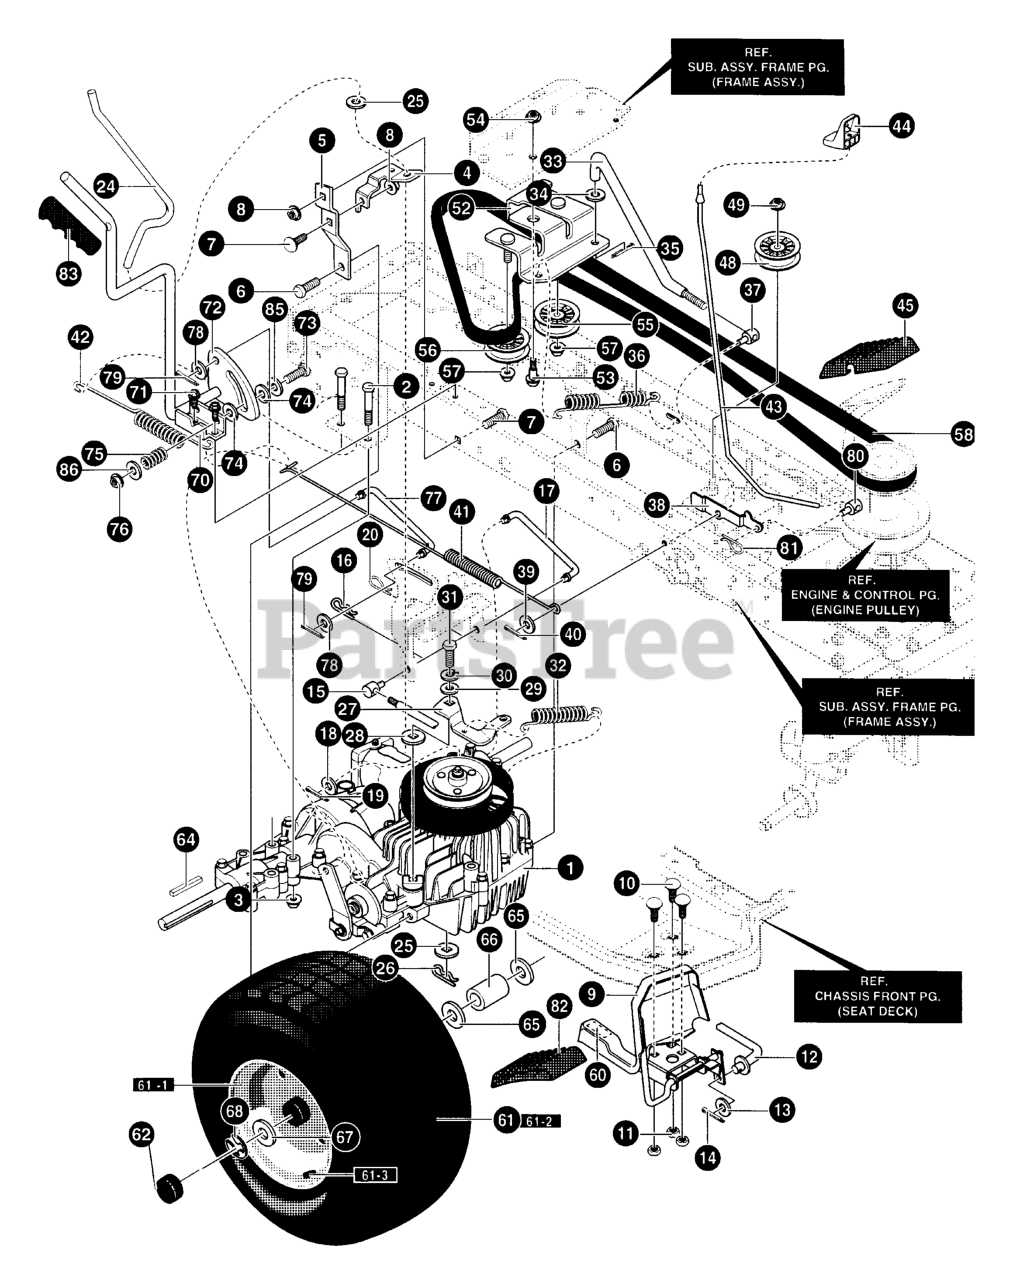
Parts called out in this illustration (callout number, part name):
1	Transaxle, Peerless **
2	SCREW, 5/16-18 x 2.50
3	NUT, 5/16- 18
4	BRACKET, DISCONNECT
5	TORQUE STRAP
6	SCREW, 5/16-18 x 0.75
7	BOLT, 5/16- 18X.63
8	NUT, 5/16- 18
9	ASSEMBLY, PEDAL
10	BOLT, 5/16- 18X.75
11	NUT, 5/16- 18
12	ROD, PEDAL LINK
13	HAIRPIN
15	NUT, Adjusting, 1/2-13
16	PIN, HAIR
17	ROD HYDRO LINK
18	WASHER, FLAT
19	PIN, COTTER
20	PIN, HAIR
24	ROD HYRO LINK
25	Washer
26	PIN, COTTER
27	ARM DISCONNECT
29	WASHER, FLAT
31	SCREW 1/4- 28X.75
32	SPRING, EXTENSION
33	ROD, CLUTCH
34	Washer
35	PIN, COTTER
36	SPRING, CLUTCH
37	NUT, ADJUSTING
38	LATCH, PARK BRAKE
39	WASHER, FLAT
40	PIN, COTTER
41	SPRING, EXTENSION
42	SPRING, TENSION
43	ROD, PARKING BRAKE
44	KNOB, PARKING BRAKE
45	PAD, CLUTCH/BRAKE
48	PULLEY, IDLER
49	NUT, 3/8- 16
52	BRACKET IDLER
53	BOLT 3/8- 16
54	NUT, 3/8- 16
55	PULLEY, IDLER
56	PULLEY, V- IDLER
57	NUT, 3/8- 16
58	MOTION DRIVE
60	PAD, TOE
61	TIRE & RIM 20X10-8
61-1	VALVE STEM
61-2	RIM, CARL
61-3	TIRE 23X9.5
62	HUB CAP
64	KEY, SQUARE
65	WASHER, FLAT
66	SPACER
67	WASHER, FLAT
68	RING, RETEX
70	BRACKET, HAND CONTROL
72	LEVER HAND CRUISE
73	BOLT 5/16- 18X.5
74	WASHER, FRICTION
75	SPRING - COMP
76	NUT, 5/16- 18
77	LINK, CRUISE CONTROL
78	Washer
79	PIN, COTTER
80	CLEVIS, PARKING BRAKE
81	PIN, COTTER
82	PAD, SPEED CONTROL PEDAL
85	WASHER, FLAT
86	WASHER, FLAT
